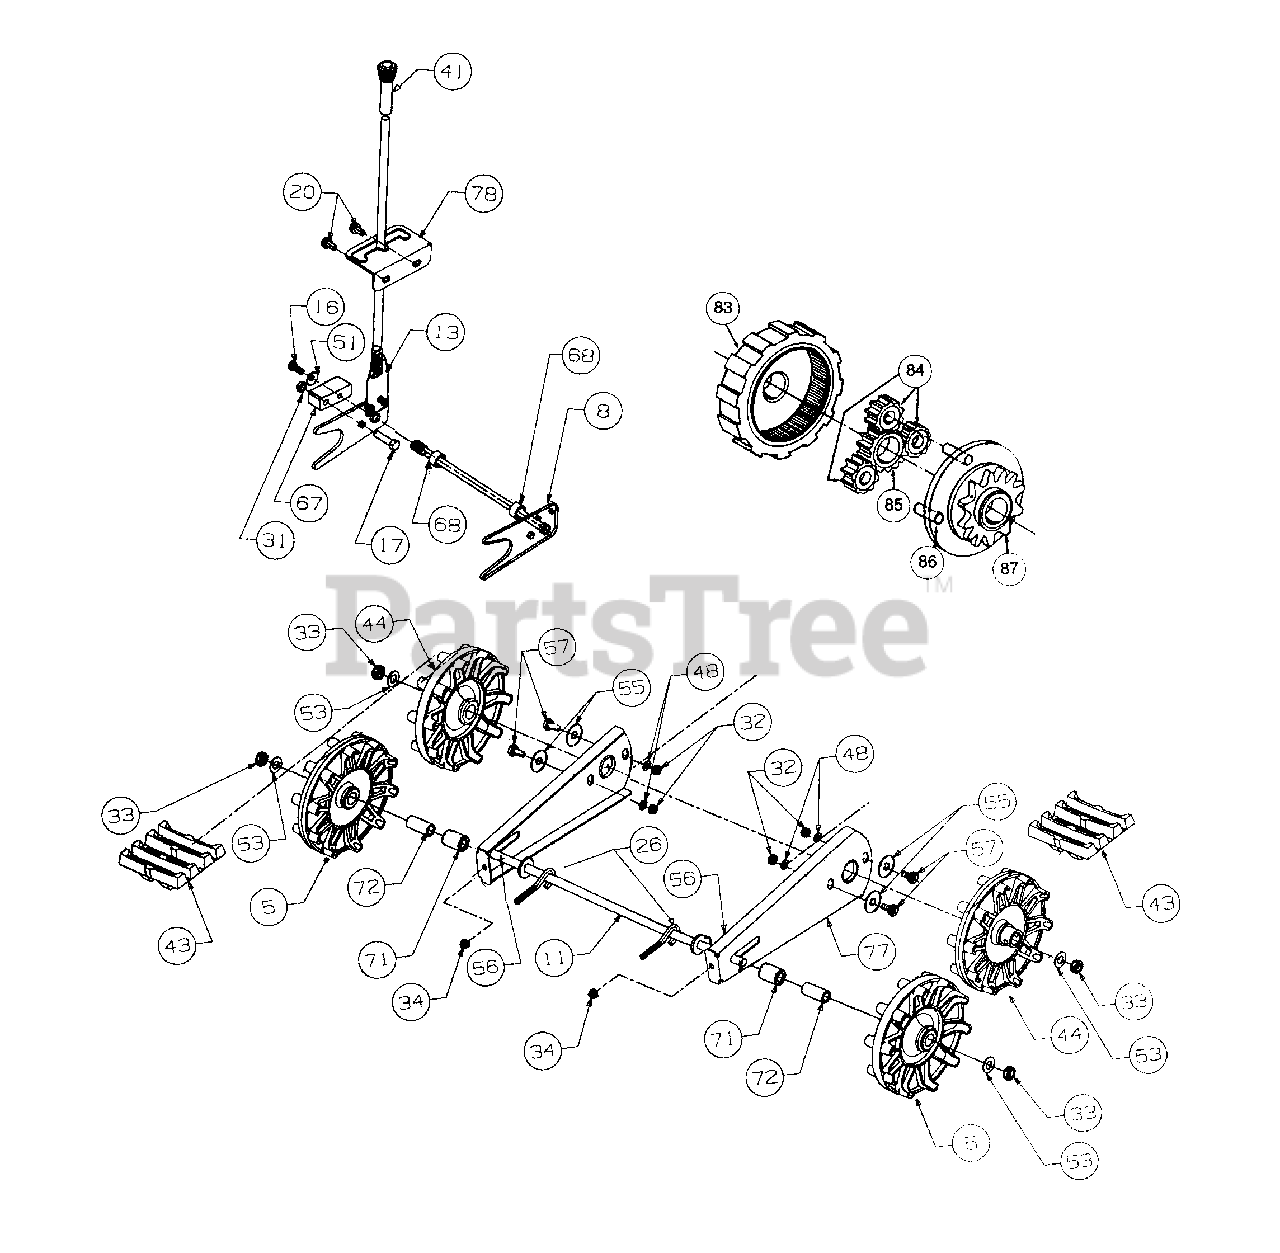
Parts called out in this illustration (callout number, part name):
5	Wheel Assembly Idler
17	Screw
20	Screw
32	Nut Hex
44	Wheel-Track Drive
48	Washer-Lock
51	Washer-Bell
53	Washer-Flat
55	Washer-Flat
56	Lubricant
57	Screw-Shoulder
67	Lift-Shaft Drive
83	Gear Ring
84	Gear 12-Tooth
85	Gear 18-Tooth
86	Pin Dowel
87	Carrier
